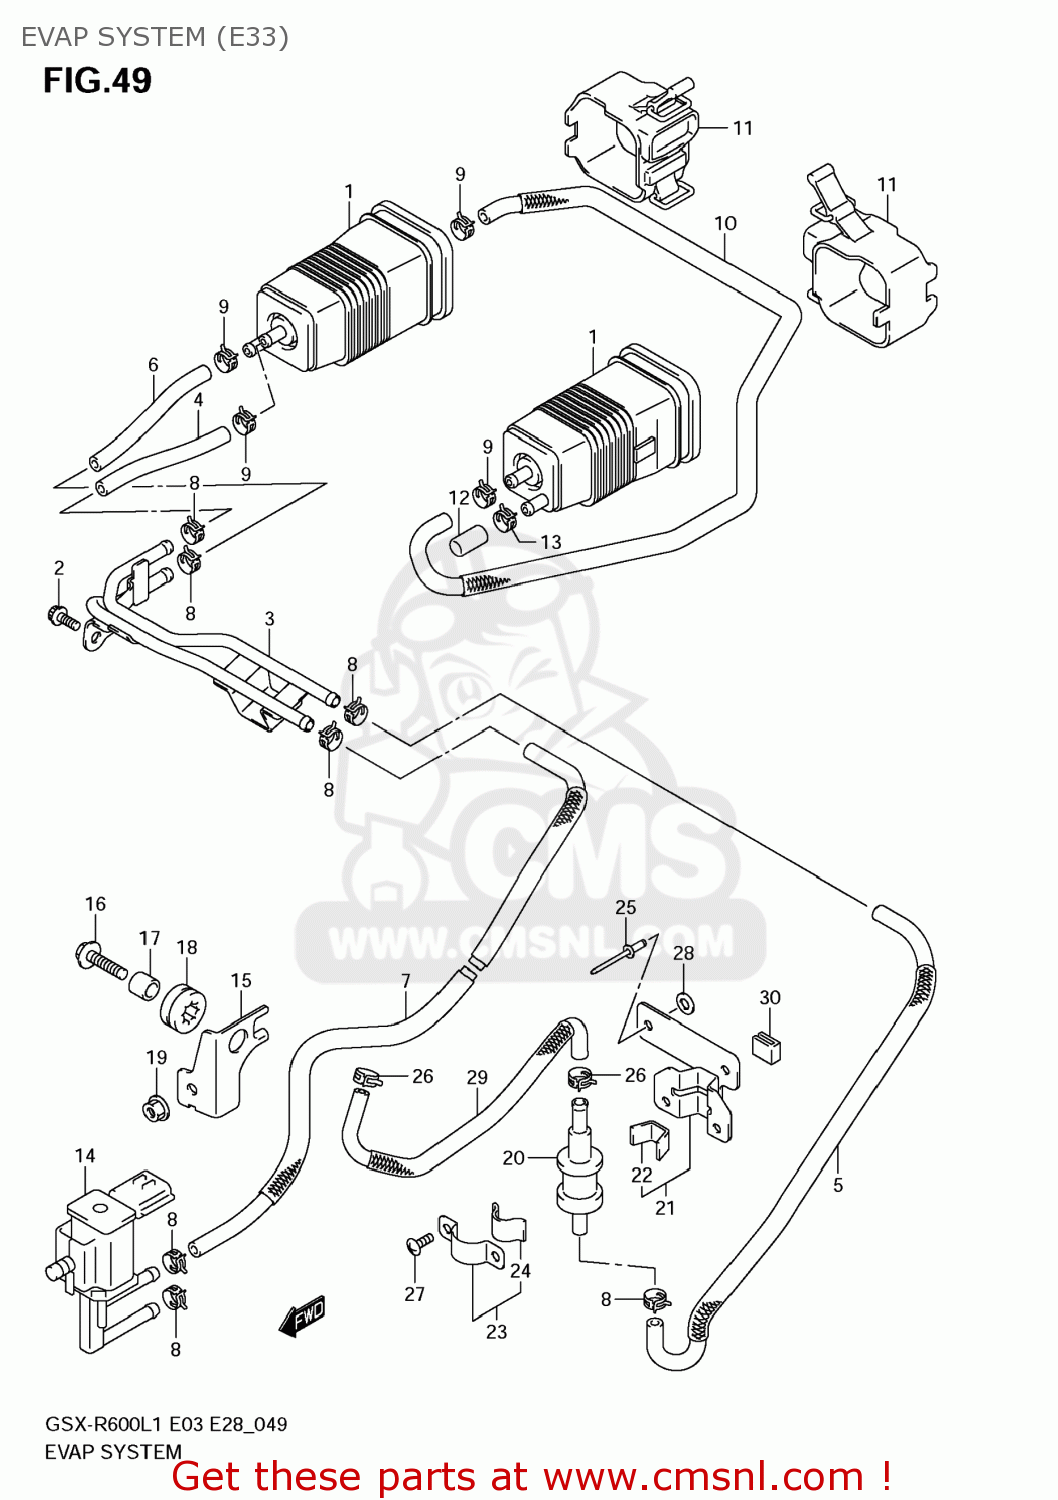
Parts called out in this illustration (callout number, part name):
1	CANISTER ASSY,CHARCOAL
2	BOLT
3	PIPE,EVAP
4	HOSE,SURGE NO.1
5	HOSE,SURGE NO.2
6	HOSE,PURGE NO.1
7	HOSE,PURGE NO.2
8	CLIP
9	CLIP
10	HOSE,CANISTER JOINT
11	CUSHION,CANISTER
12	CAP,OD:11.5
13	CLIP
14	VALVE ASSY,DUTY FOR PURGE
15	BRACKET,PURGE VALVE
16	BOLT(6X30)
17	SPACER(6.5X10X11.6)
18	CUSHION
19	NUT
20	VALVE,FUEL TANK BREATHER
21	PLATE,BREATHER VALVE
22	CUSHION
23	PLATE,FUEL TANK BREATHER NO.2
24	CUSHION
25	RIVET
26	CLIP
27	SCREW
28	WASHER
29	HOSE,TANK & BREATHER VALVE
30	CUSHION
